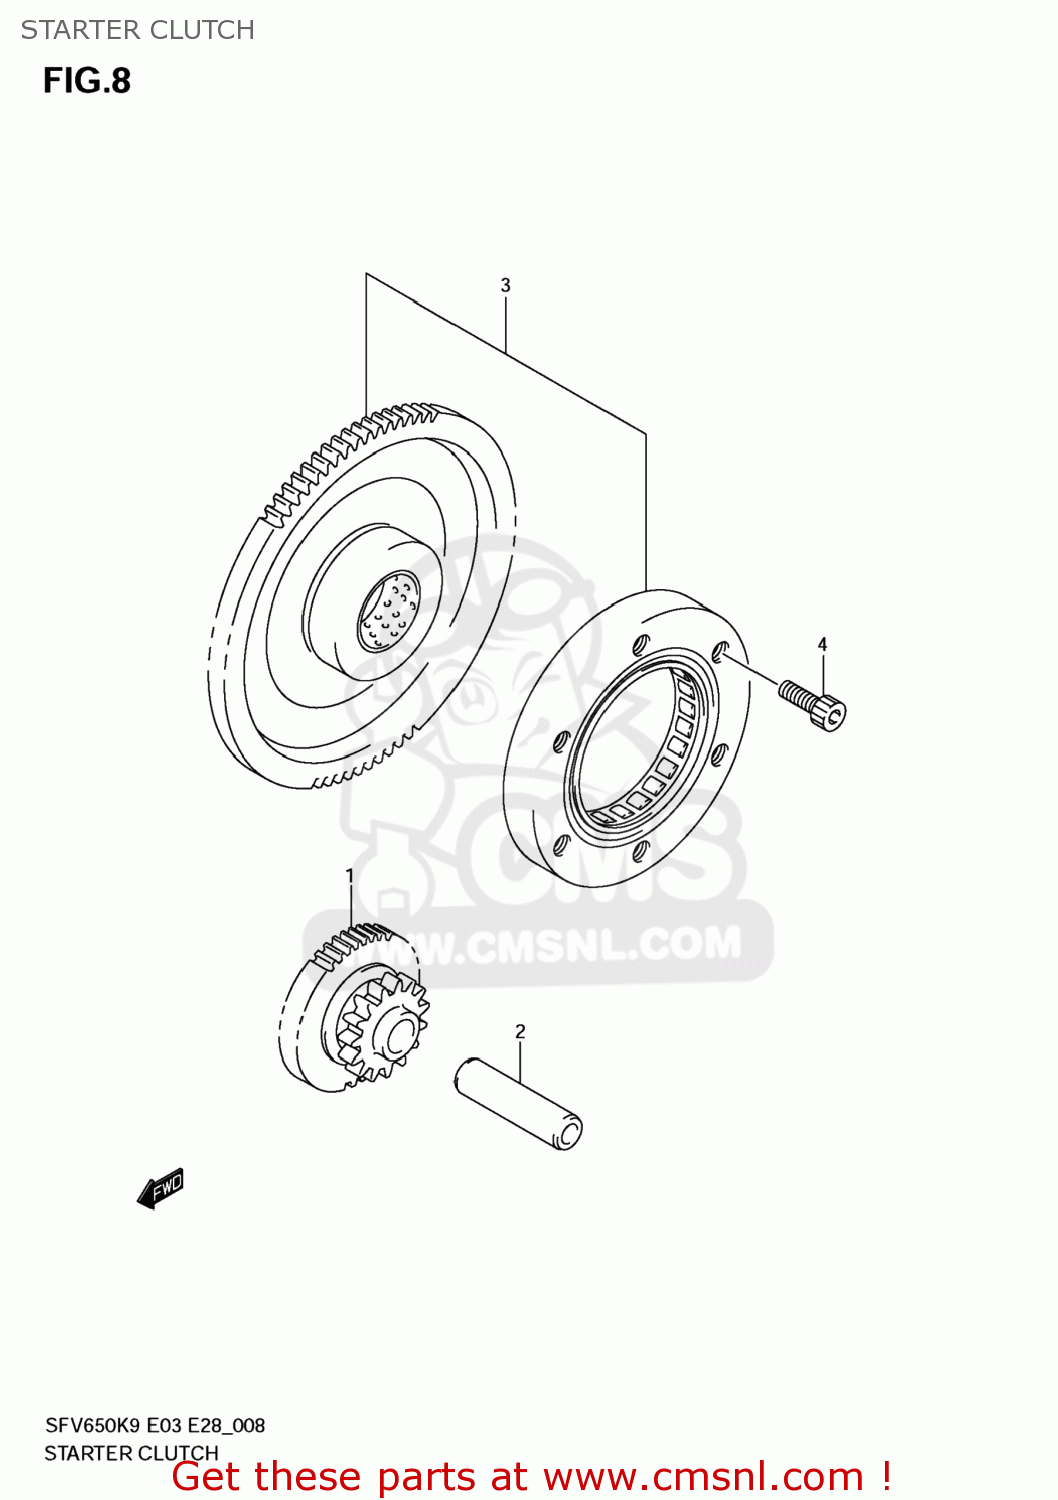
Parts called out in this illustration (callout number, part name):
1	GEAR,STARTER IDLE
2	PIN(8X12X45.5)
3	CLUTCH SET,STARTER
4	BOLT(8X16)
